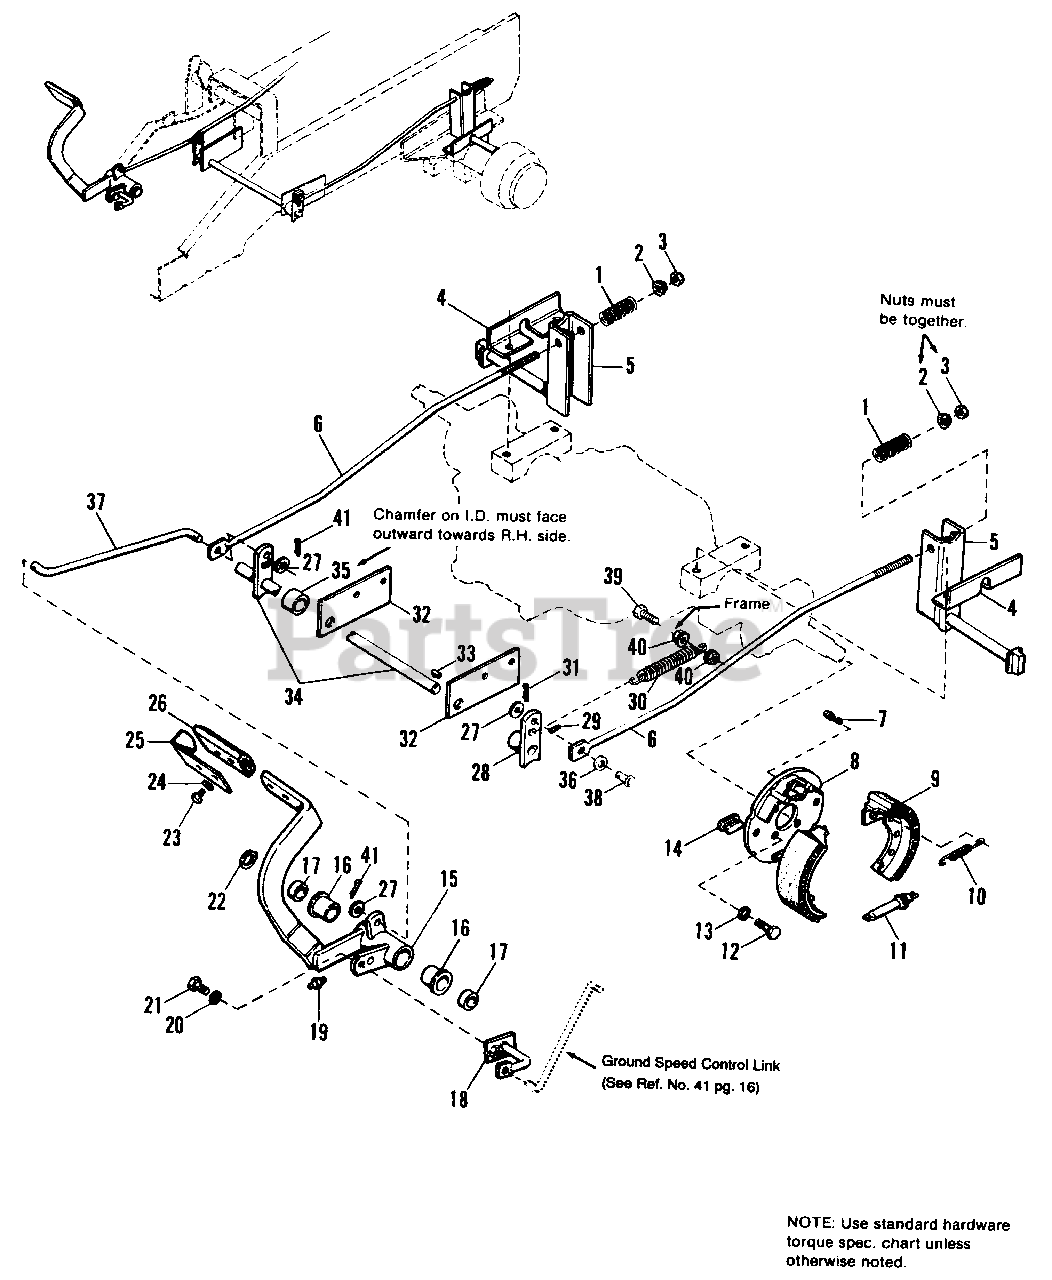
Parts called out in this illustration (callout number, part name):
1	SPRING, Compression
2	NUT, Large Flange, 1/2-13
3	NUT, Hex, 1/2-13
4	SUPPORT, Actuator
5	ACTUATOR ASSY.
6	ROD ASSY. (Incl. Ref. Nos. 36 & 38)
7	SPRING, Extension
8	BRAKE SUPPORT ASSY.
9	BRAKE SHOE & PAD ASSY.
10	SPRING, Extension
11	SCREW ASSY., Brake Adjusting
12	CAPSCREW, Hex Hd., 3/8-16 x 1
13	LOCKWASHER, 3/8
15	LEVER ASSY., Brake, L.H.
16	BUSHING, 1-1/4 x 1-3/4 x 1
18	ROD & PLATE ASSY. Lock
19	FITTING, Lube, 1/4" Drive
20	LOCKWASHER, 5/16
21	CAPSCREW, Hex Hd., 5/16-18 x 3/4
22	RING, Retaining
23	CAPSCREW, Hex Hd., 1/4-20 x 3/4
24	LOCKWASHER, 1/4
25	SUPPORT, Pedal
27	WASHER, Plain, 13/32 x 7/8 x 5/64
28	LEVER ASSY., Brake
29	SETSCREW, Sq. Hd., 5/16-18 x 1/2
30	SPRING, Extension
31	PIN, Cotter, 1/8 x 3/4
32	SUPPORT, Brake Cross Shaft
33	KEY, Woodruff #9
34	SHAFT ASSY., Brake Pivot
35	SPACER, Special
36	WASHER
38	PIN, Brake Rod
39	CAPSCREW, Hex, 5/16-18 x 1-1/4
40	NUT, Hex, Flange Lock, 5/16-18
41	PIN, Cotter, 1/8 x 3/4
